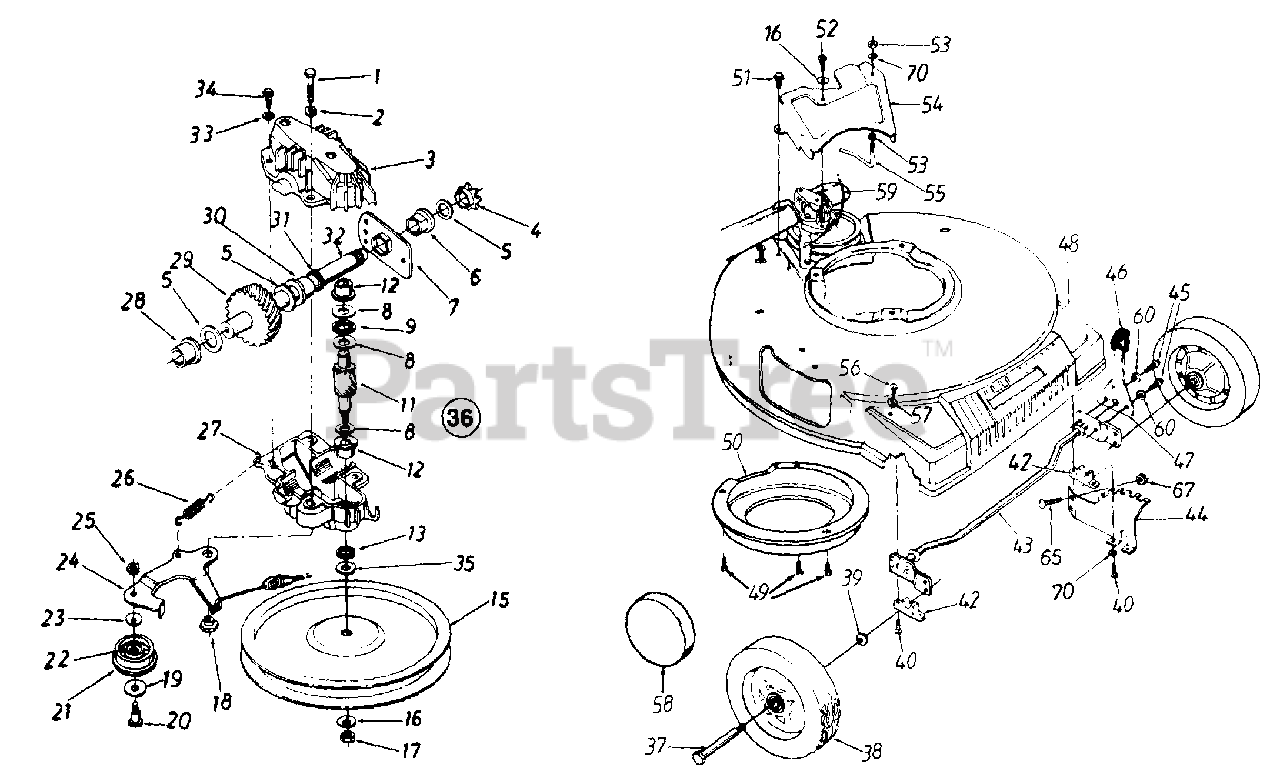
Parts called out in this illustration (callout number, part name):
1	Hex Patch Bolt 1/4-20 x 1.25"
2	L-Wash. 1/4" I.D.
3	Upper Hsg. Half
4	#48 Sprocket 7 T x 1/2 Pitch
5	Fl-Wash. 5/8" I.D. x .030
6	Hex Flange Brg. .631" I.D.
8	Thrust Wash. .382" I.D. x .70" O.D.
9	Thrust Bearing .375" I.D. x .812" O.D.
11	11 Tooth Pinion Shafts
12	Flange Bearings
15	Fl-Pulley 5.06" O.D.
16	Bell-Wash. .265" I.D. x .75"
17	Hex L-Nut 1/4-28 L.H. Thd.
18	Shld. Spacer .375" Dia. x .170
19	Fl-Wash. .390" I.D. x 1.0"
20	Shld. Bolt .375" Dia. x .40"
21	Fl-Idler Plastic 1.50" Dia.
22	Needle Brg. .375" x .31
24	Idler Brk't. Ass'y.
25	Hex Patch L-Nut 1/4-28 Thd.
26	Extension Spring 1.12" Lg.
27	Lower Hsg. Half
28	Flange Bearing .566 Dia.
29	33 Tooth Helical Gear
30	Flange Bearing .629 Dia.
31	Oil Seal .625 Dia.
32	Gear Sprocket Shafts
33	L-Wash. #10 I.D.
34	Hex B-Tap Scr. #10 x .62"
35	Hex Washer .26" x .88"
36	Transmission Comp.
37	Front Axle Bolt
38	Wheel Ass'y. Comp.
39	Bell-Wash. .380" 1.0. x .88
40	Hex Wash. Hd. Scr. 1/4 x 1" Lg.
42	Block Bushing
45	Hex TT-Tap Scr. 1/4-20 x .38"
46	Knob
47	Spring Lever
48	Plastic Front End
49	Hex B-Tap Scr. 1/4" x .38"
52	Hex Wash. Hd. B-Tap Scr. 1/4 x .62" (Spec.)
53	Hex Nut 1/4-20 Thd.
56	Torx Truss Hd. Scr. 5/16 x .75"
57	Bell-Wash. .345" I.D. x .88"
58	Hub Cap
59	S.P. Cable
60	External L-Wash. 1/4" I.D.
65	Carr. Bolt 1/4-20 x .5" Lg.
67	Hex Flange L-Nut 1/4-20 Thd.
70	L-Wash. 1/4" I.D.
